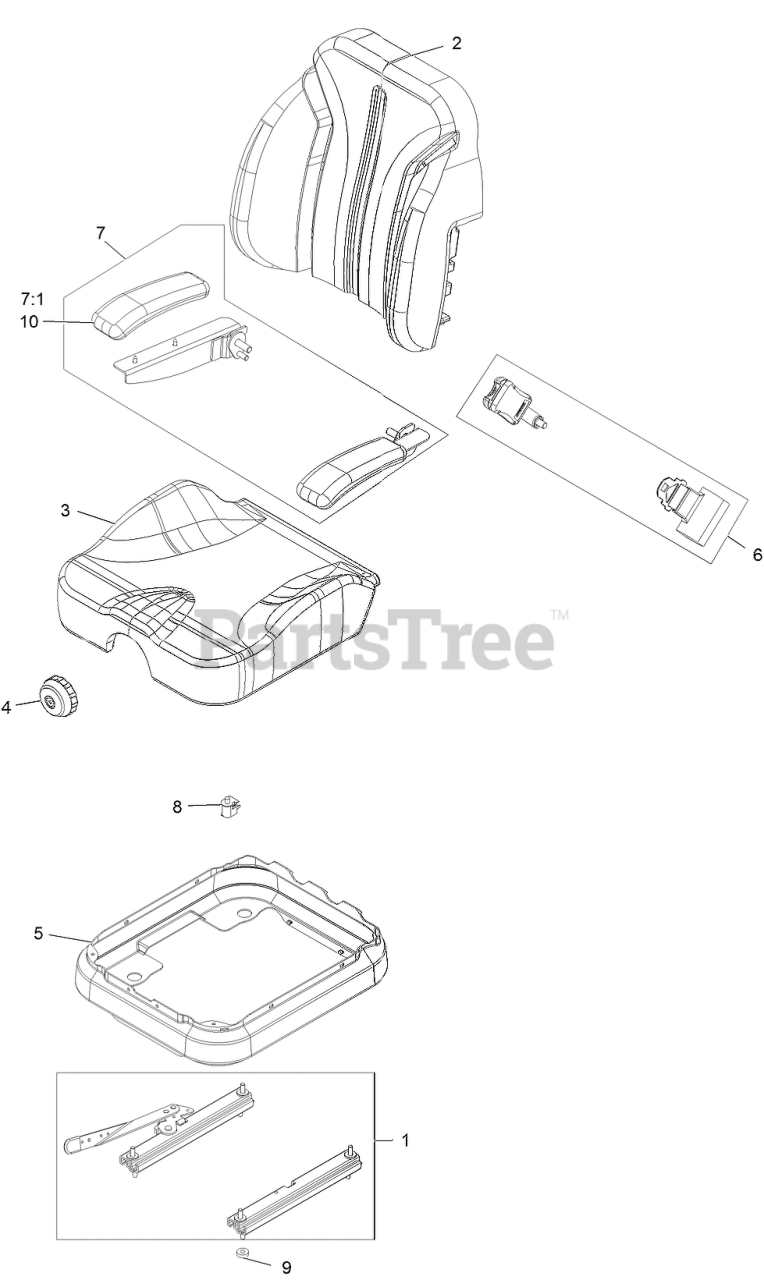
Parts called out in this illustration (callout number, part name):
1	TRACKS-4" TRAVEL
2	COVER-SEAT BACK SVC
3	COVER-SEAT BOTTOM SVC
4	KNOB-ADJUSTER
5	BELLOWS-SEAT
6	KIT-SEAT BELT
7	ARMREST KIT
7:1	CUSHION-REST, ARM
8	SWITCH-BAIL
10	CUSHION-REST, ARM
